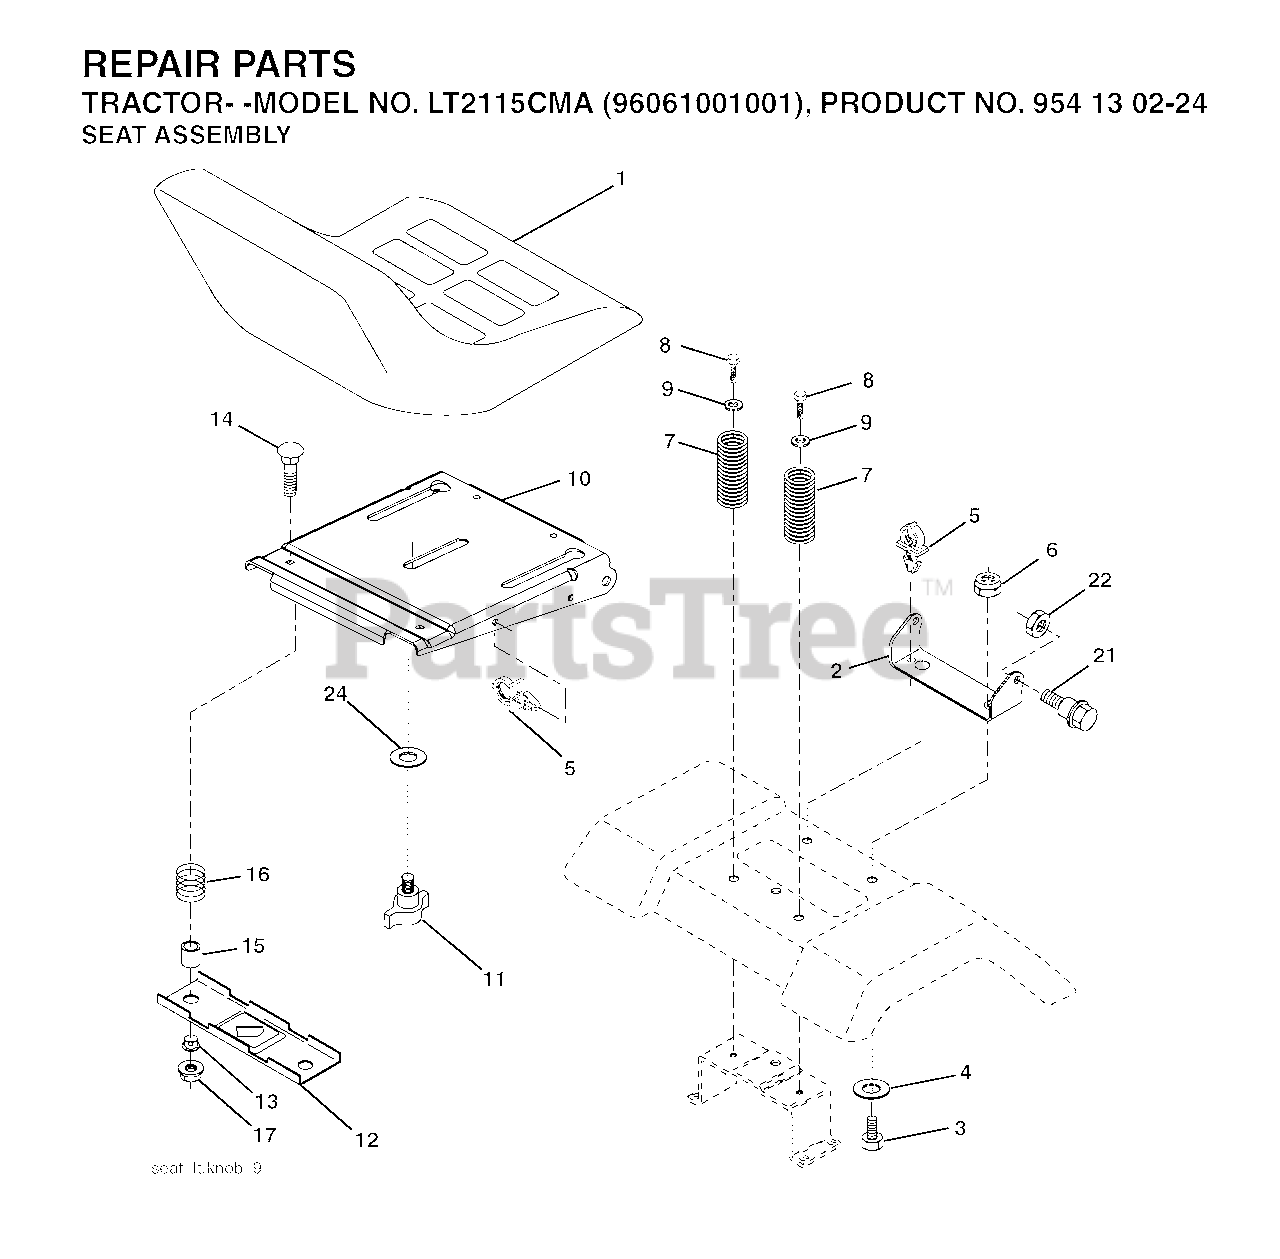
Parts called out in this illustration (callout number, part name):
2	BRKT.PIVOT.FENDER
4	WASHER PM
5	PUSH CLIP
6	NUT
7	SPRING COMPRESSION
8	SCREW 3/8-16X1
9	WASHER
11	KNOB.SEAT.ADJ.WINGNUT
12	BRKT SWITCH
14	BOLT.ROUND.HEAD.SQUARE.NECK
15	SPACER SPLIT 28X.96
17	NUT T
21	BOLT.SHOULDER.5/16-18
22	NUT.71038.31-18.HEX.NYLOCK
